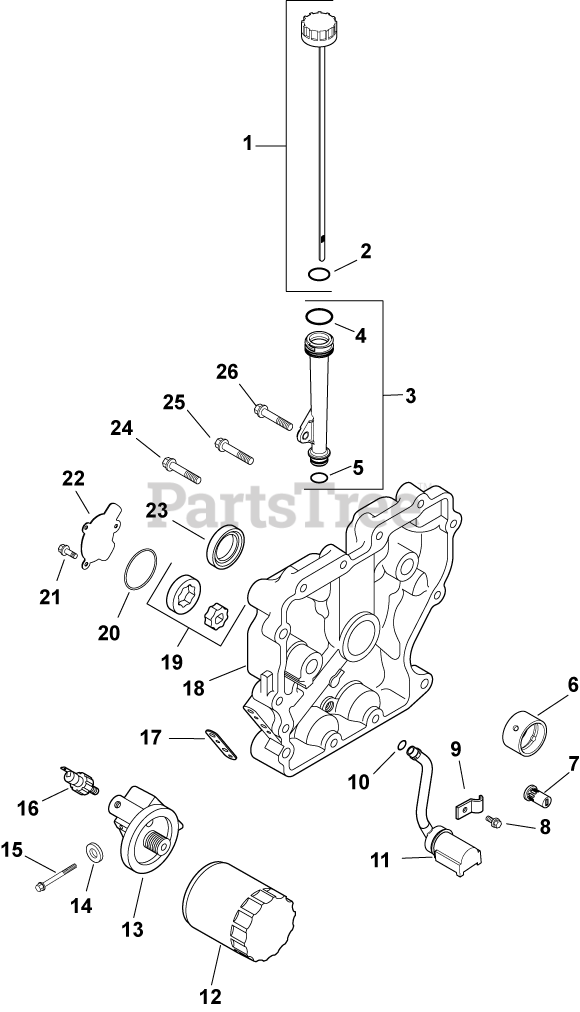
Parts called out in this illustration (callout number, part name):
1	KIT, OIL FILL CAP ASSEMBLY
2	O-RING - USE 25 153 02-S
3	TUBE, OIL FILL - PLASTIC
4	O-RING, UPPER OIL FILL TUBE
6	BEARING, CRANKSHAFT
7	VALVE, OIL PRESSURE RELIEF
8	SCREW,FLG THD FRM M5X0.8X16-(#25086398S)
10	O-RING (.5" DIA)
11	KIT, OIL PICK-UP
12	OIL FILTER
13	ADAPTER - DISCONTINUED
15	SCREW, FLG M6X1.0X60
16	SENSOR, OIL PSI
17	GASKET, OIL FILTER ADAPTER
18	CLOSURE PLATE ASSEMBLY - DISCONTINUED
19	PUMP ASSEMBLY, OIL
20	O-RING (2.5" DIA)
21	SCREW,FLG THD FRM M5X0.8X16-(#25086398S)
22	COVER, OIL PUMP
23	SEAL, OIL
24	SCREW, FLG M8X1.25X45
25	SCREW, HEX FLANGE -USE 24 086 17-S
26	SCREW, SPECIAL HEAD
